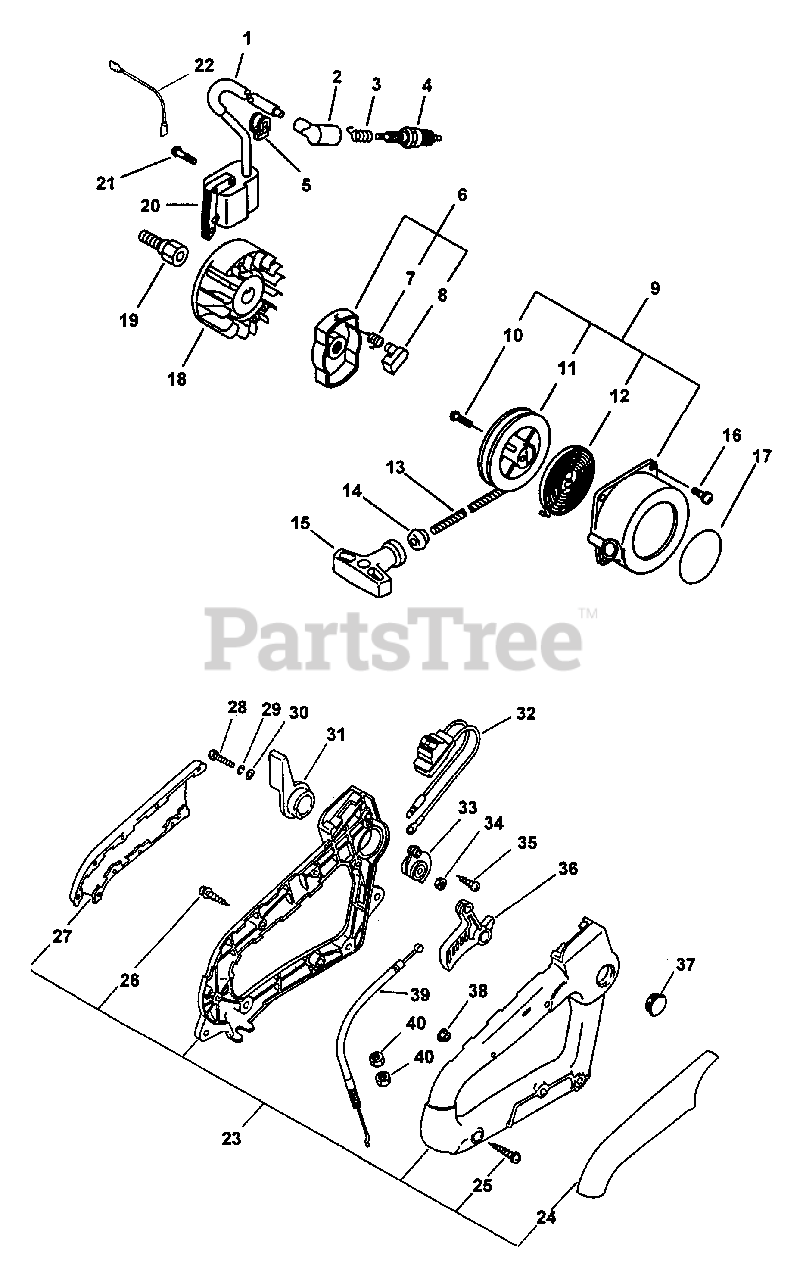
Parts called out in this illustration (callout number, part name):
2	CAP, SPARK PLUG
3	TERMINAL, SPARK PLUG CAP
4	SPARK PLUG -- BPM-7Y
6	STARTER PAWL ASSY
7	SPRING, RETURN
8	PAWL, STARTER - BLACK
9	STARTER ASSY
11	REEL, ROPE
12	SPRING, REWIND
13	RePower BULK ROPE - 200 FEET
14	GUIDE, ROPE
15	GRIP, STARTER
16	SCREW - 4X22
17	LABEL - ECHO
18	FLYWHEEL
19	HUB, FAN
20	COIL, IGNITION
21	SCREW - 4X22
22	LEAD - GROUND
23	HANDLE SET - REAR
24	GRIP, HANDLE - RIGHT
25	SCREW - 5X35
26	SCREW - 4X22
27	GRIP, HANDLE - LEFT
28	SCREW - 6X20
29	LOCKWASHER - 5
30	WASHER - 6
31	CONTROL, THROTTLE
32	IGNITION SWITCH ASSY
33	BRACKET, THROTTLE
34	LOCKNUT - 6
35	SCREW - 4X10
36	TRIGGER, THROTTLE
38	NUT - 5 -- FLANGE
39	CABLE, THROTTLE
